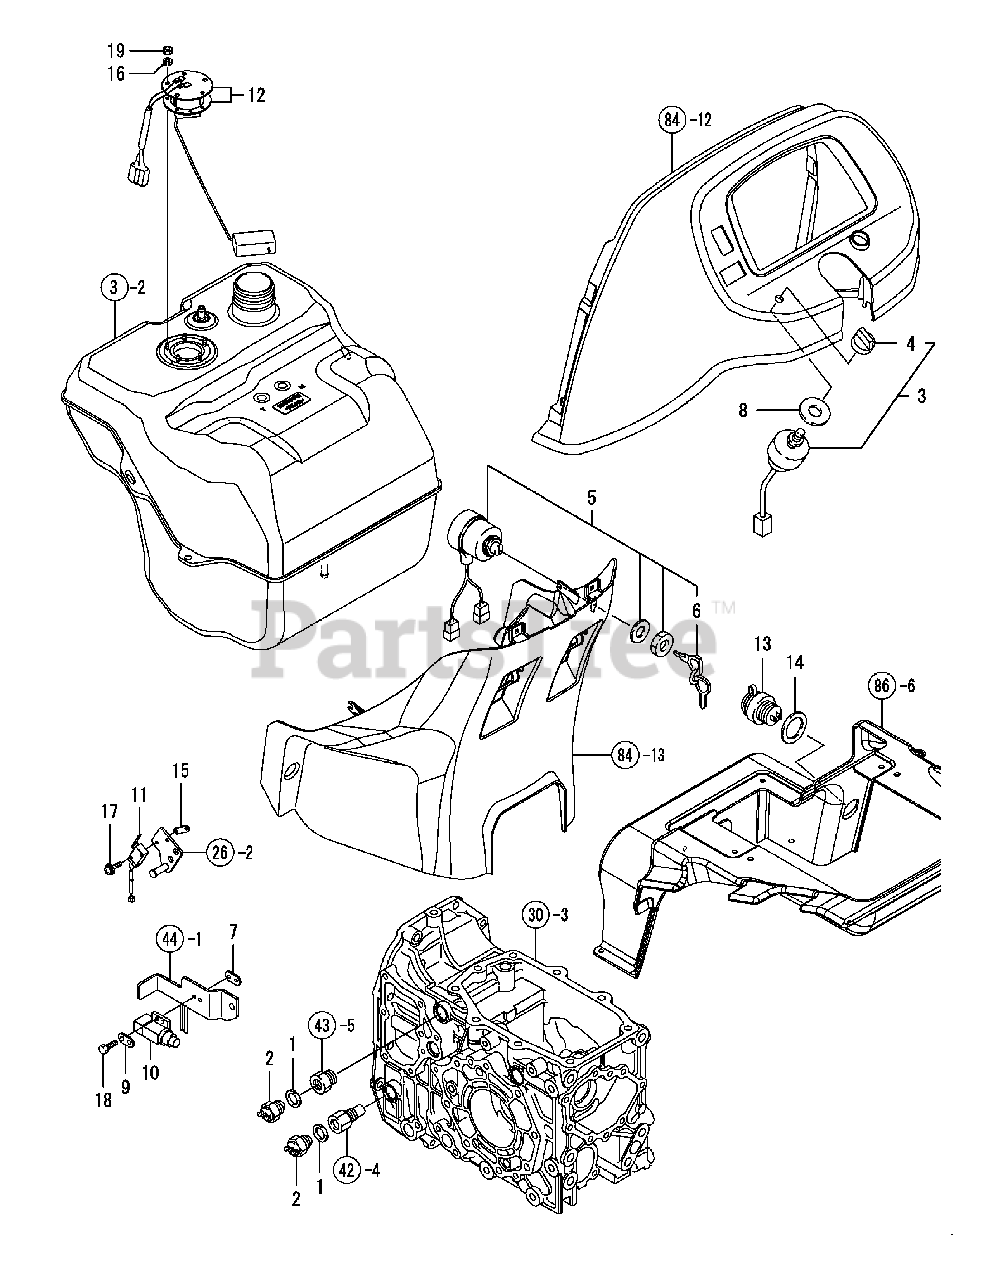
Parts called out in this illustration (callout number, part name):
2	Switch, Neutral
3	Switch, Cmp Lighting
5	Switch, Starting
7	Nut,Switch 2-M4
10	Stop Lamp Sw,Delta
11	Switch, P. Brake
12	Gauge, Fuel Oil
13	DC Power Outlet
15	Nut 2-M3, Switch
